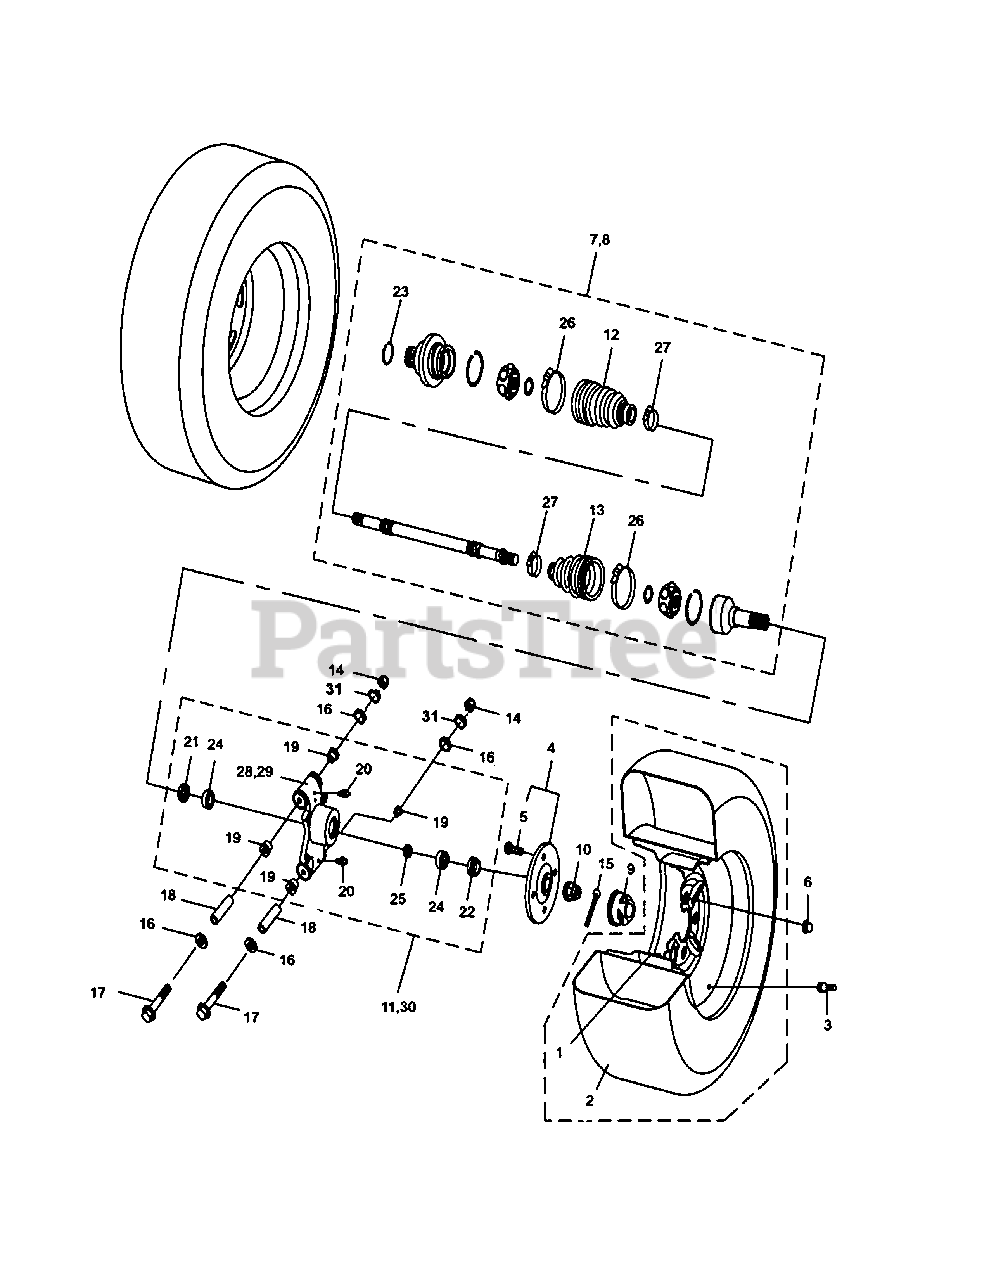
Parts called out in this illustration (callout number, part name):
1	Rear Alu. Wheel F116
3	Cycle Valve
4	Rear Hub
6	Nut M10
7	Rear Left C.V Axle
8	Rear Right C.V Axle
9	Wheel Caps III
11	Rear Right Knuckle Assy
12	Inner Rubber Dust-P Cover (C-1520)
13	Inner Rubber Dust-P Cover (C-1605)
14	Hexagon flange nut M10×1.25
15	Cotter Pin 3.2×50
16	Dust P. Cover
17	Bolt M10×1.25×110
18	Axle Sleeve,Liner
19	Sleeve For Knuckle
20	Refueling Nozzle M6
21	Inner Oil Seal, Rear Knuckle 38×62×8
22	Outer Oil Seal, Rear Knuckle 42×62×7
23	Circlip
24	Bearing 6206, Rear Knuckle
26	CV Boot Proof Clamp A
27	CV Boot Proof Clamp B
28	Front Left Steering Knuckle
29	Front Right Steering Knuckle
30	Rear Left Steering Knuckle Assy
31	Washer13×24×2
